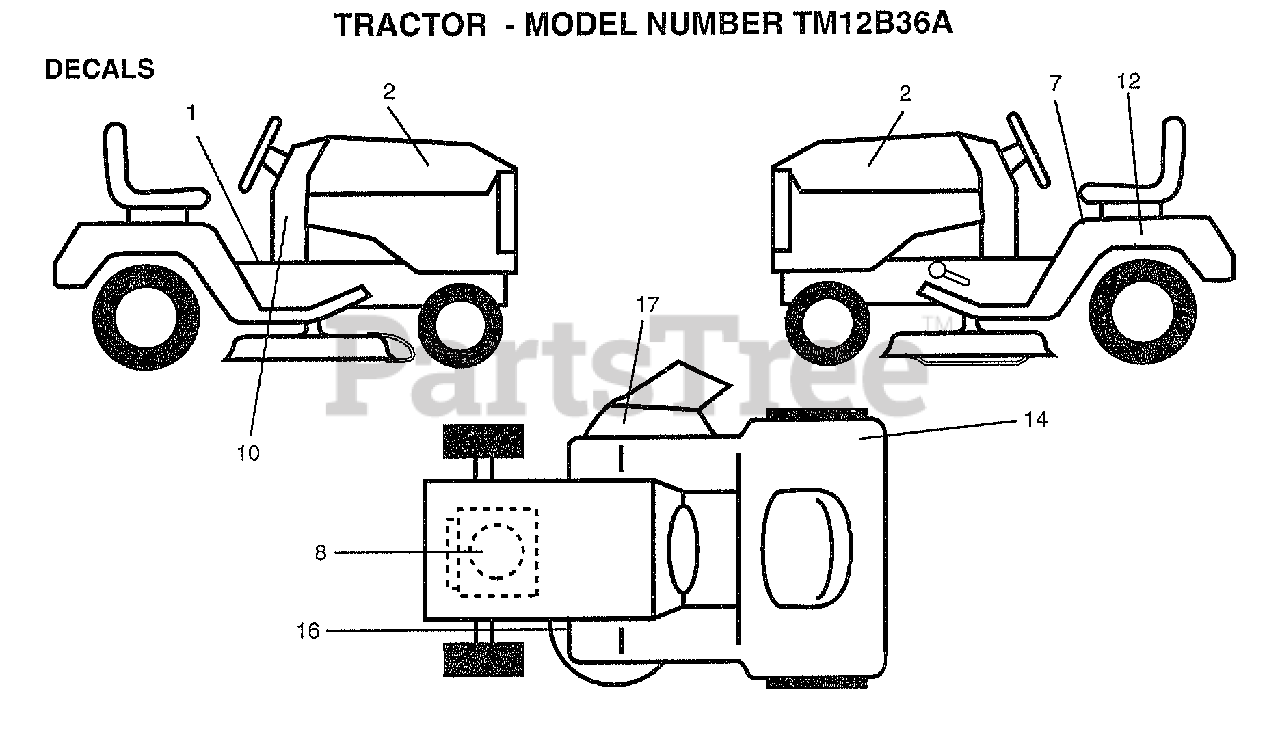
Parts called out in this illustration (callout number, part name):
1	DECAL CLUTCH/BRAK
2	"DECAL HOOD,STRIPE"
3	"DECAL CHASSIS,HOT"
7	DECAL.READ.O.MANU
8	DECAL, HP ENGINE
10	DECAL.EURO.ST.CE.
12	DECAL.BATRY.3-3908
16	DECAL.DANGER.CUTF
17	DECAL.V.BELT
